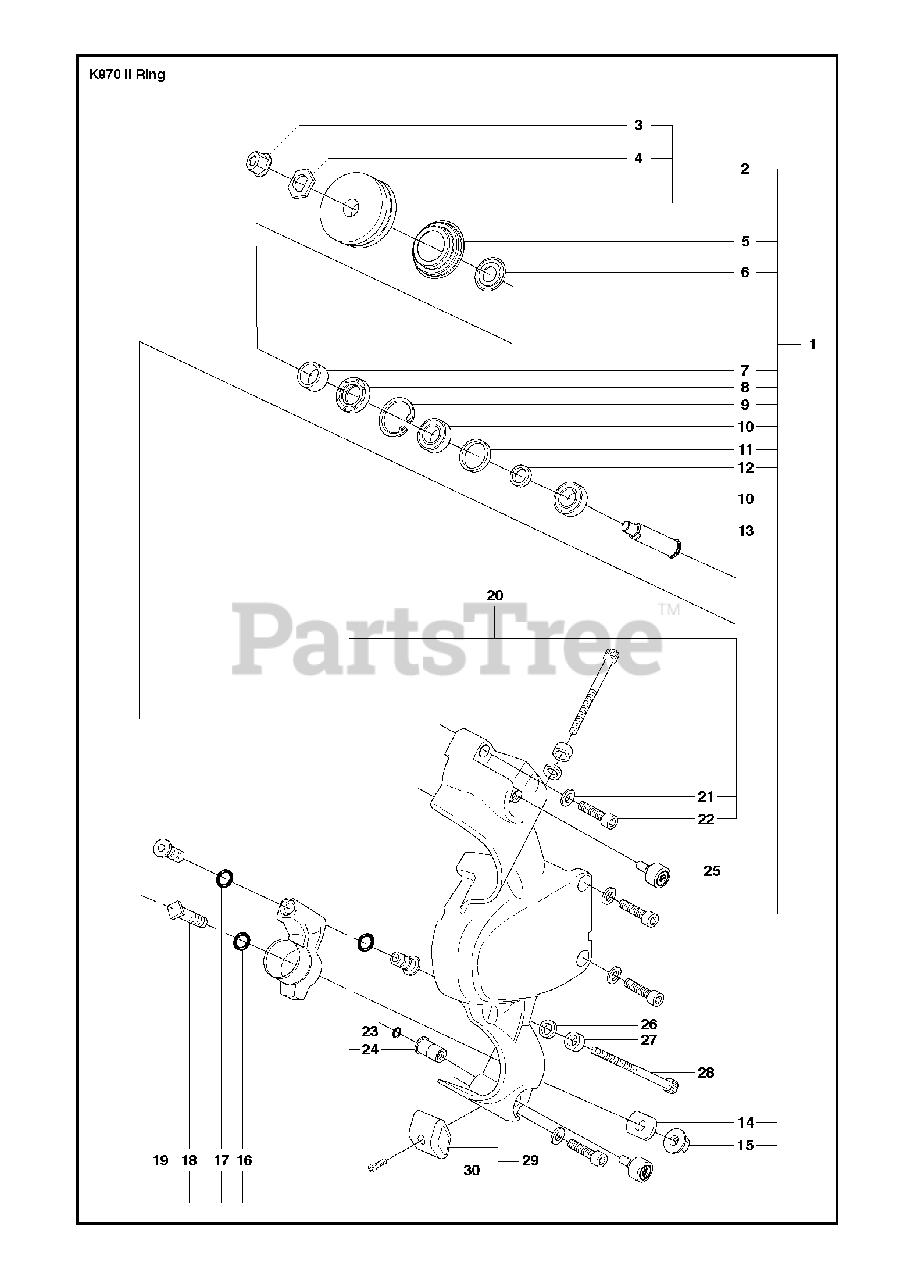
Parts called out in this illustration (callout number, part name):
1	LEVER ASSYIncl. 2, 5 - 18
2	SUPPORT ROLLERIncl. 3, 4
3	NUTFine thread
10	BALL BEARING
29	WEAR PROTECTIONIncl. 29
